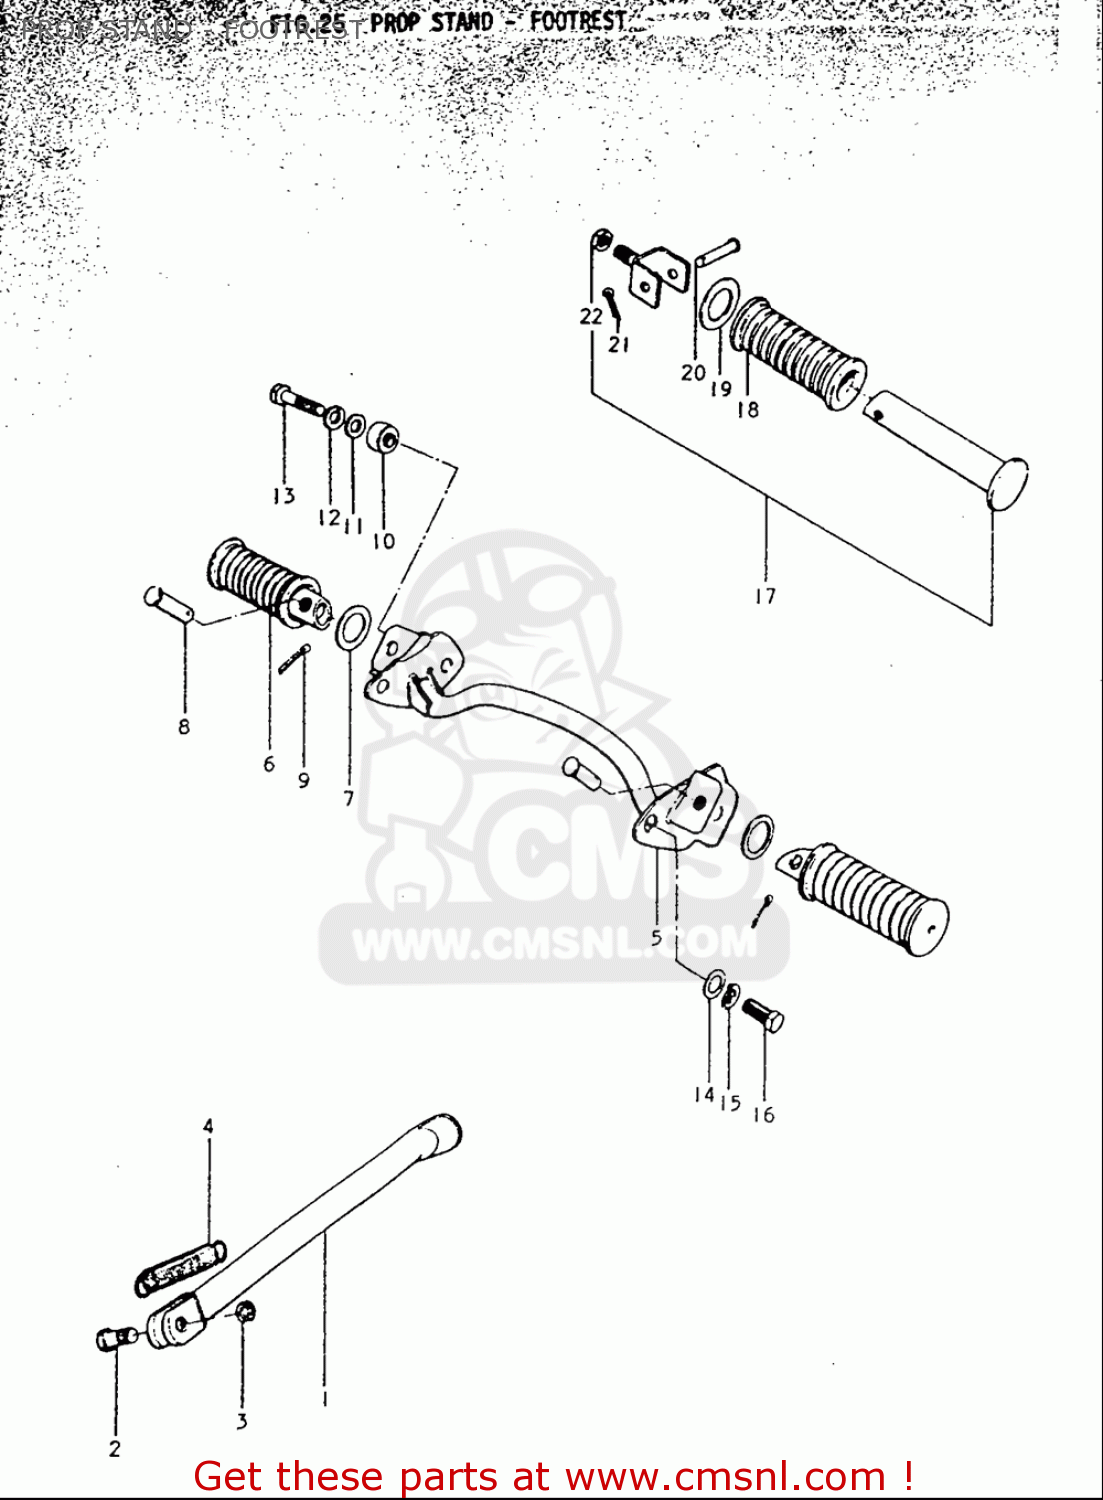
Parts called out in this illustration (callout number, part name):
2	BOLT(10X27)
3	NUT
4	SPRING
7	WASHER(22.5X38X1)
8	PIN
9	PIN
11	WASHER
12	WASHER,LOCK
13	BOLT
14	WASHER
15	WASHER,LOCK
16	BOLT
17	FOOTREST ASSEMBLY,REAR
18	RUBBER,PILLION FOOTREST
19	WASHER(19.5X32X2)
20	PIN
22	NUT
